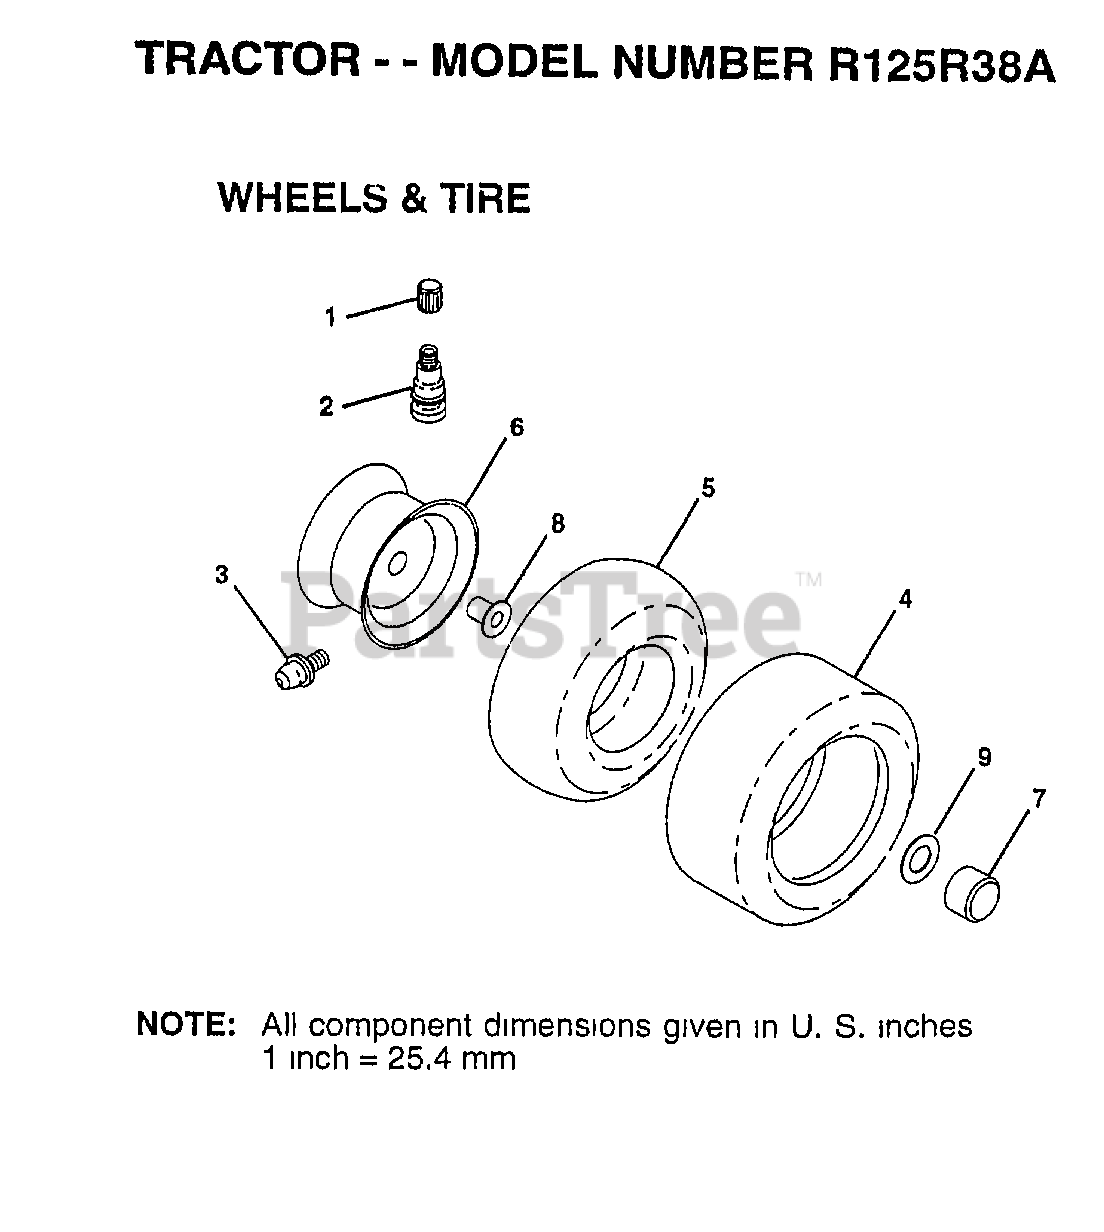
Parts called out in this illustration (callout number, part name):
1	VALVE CAP
2	VALVE STEM LT
3	FITTING LT
5	TUBE.16X6.5/7.5-8
5	TUBE.5.3/4.5/6
6	"RIM FRONT 6"""
6	"RIM ASM REAR 8"""
7	HUB CAP
8	"FLANGE, BEARING"
9	WASHER
